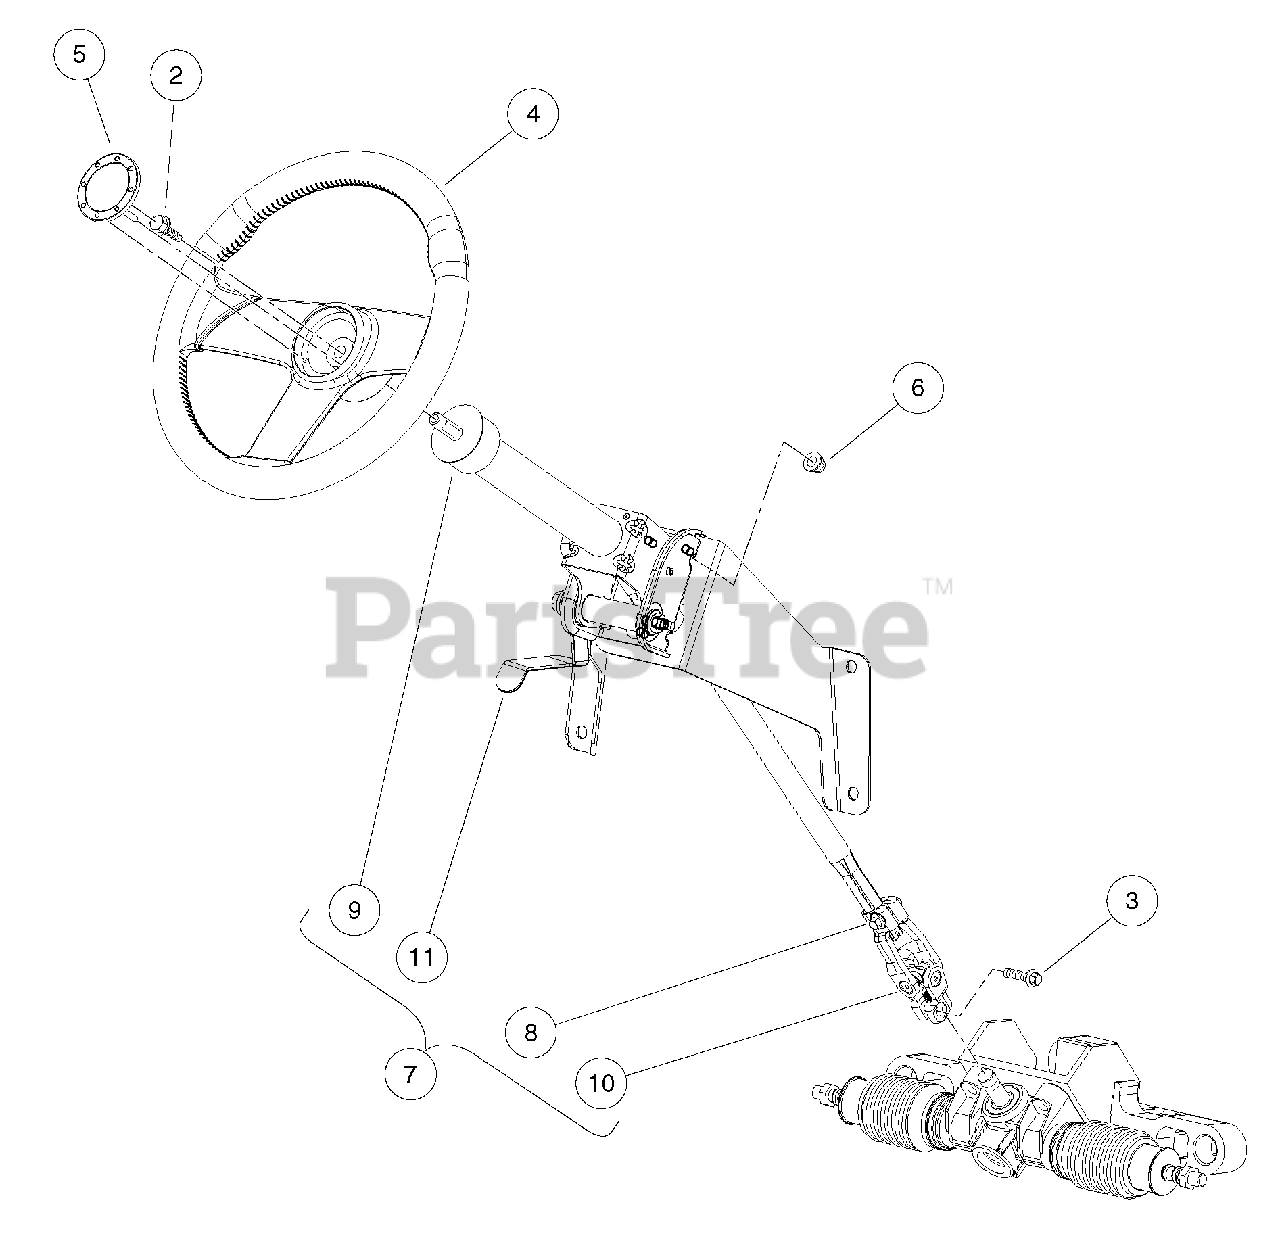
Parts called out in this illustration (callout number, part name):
1	Instl, Steering System
2	Bolt, M10 X 20 Hex Washer Hd
3	Bolt, Flange Head, M8 X 30.0
4	Steering Wheel, Viper, Hex Hub
5	Cap, Steering Wheel, Viper
6	Lock Nut, Flg M8 X 1.25 Nylon
7	Steering Column
8	Bolt, Flange Head, M8 X 30.0
9	Shroud, Steering Column
10	Bolt, M4 X .7 X 60
11	Handle, Steering, Tilt
